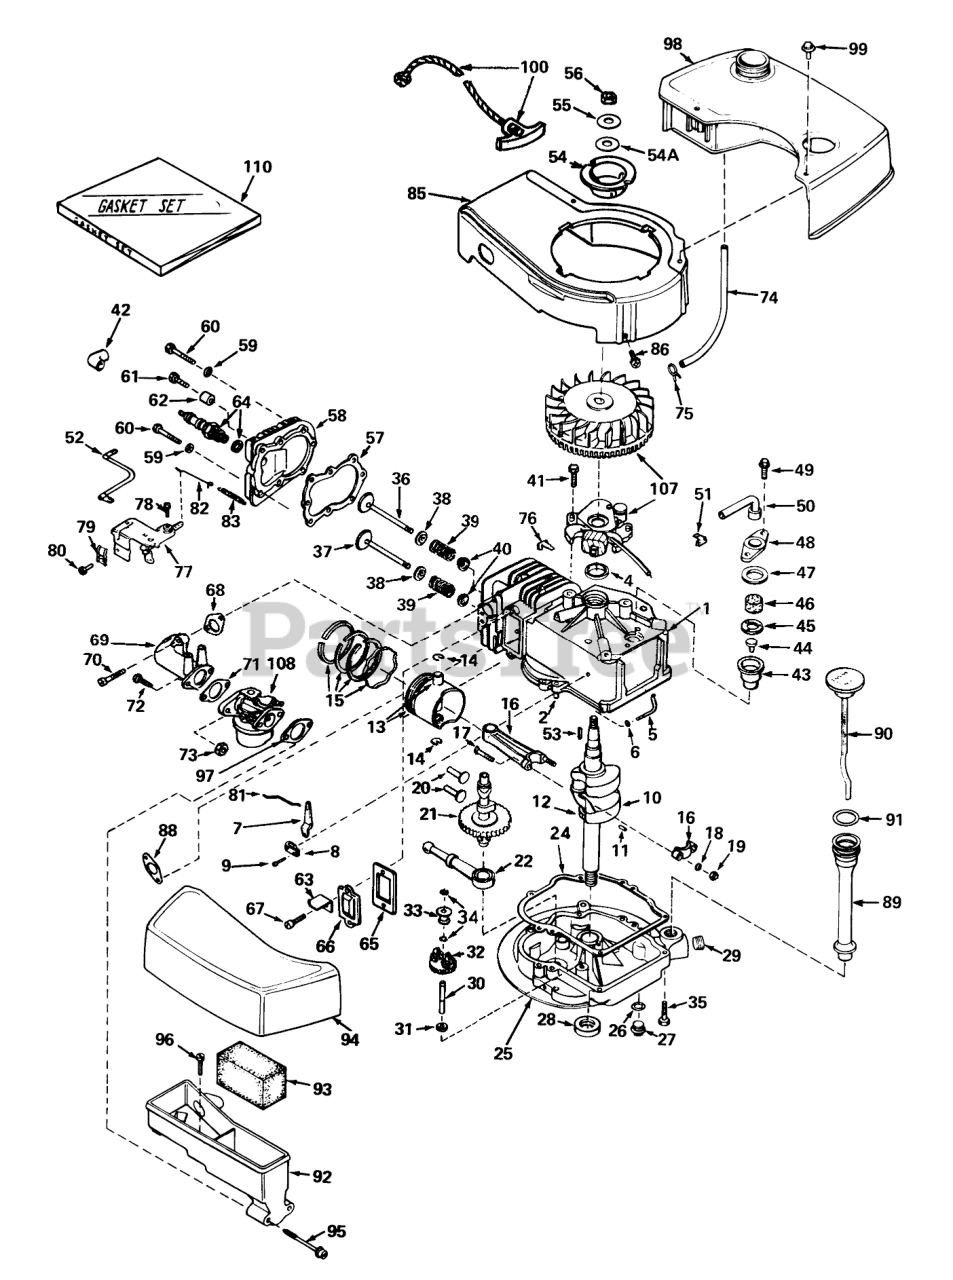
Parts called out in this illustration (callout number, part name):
1	Cylinder Assembly (Incl. Nos. 2, 4 and 87)
2	Pin-Dowel
4	OIL SEAL
5	Rod Governor (Incl. No. 6)
6	Washer-Flat
7	Governor Lever
8	Clamp-Lever, Governor
9	Screw
10	Crankshaft (Incl. Nos. 11 and 12)
11	Pin, Groove
12	Gear, Crankshaft
13	Piston & Pin Assembly (Incl. 2 of No. 14) (Standard)
13	Piston & Pin Assembly (Incl. 2 of No. 14) (.010 Oversize)
13	Piston & Pin Assembly (Incl. 2 of No. 14) (.020 Oversize)
14	Ring-Retaining, Piston Pin
15	Ring Set Piston (Std.)
15	Ring Set Piston (.010 Oversize)
15	Ring Set Piston (.020 Oversize)
16	Rod Assembly, Connecting (Incl. Nos. 17, 18 and 19)
17	Bolt, Connecting
19	LOCKNUT
20	Lifter-Valve
21	Camshaft (Mech. Compression Release)
22	Oil Pump ASM
24	Gasket, Mounting
25	Flange Assembly, Mounting (Incl. Nos. 27 thru 30)
26	Gasket-Oil Drain
27	Plug Oil Drain
28	Seal Oil
29	Plug Oil Drain
30	Shaft-Governor
31	Washer-Flat
32	Governor Gear ASM
33	Spool-Governor
34	Ring-Retaining
35	Screw (1/4-20 x 1-1/4)
36	Valve, Intake (Incl. Nos. 38 thru 40) (Standard)
36	Valve, Intake (Incl. Nos. 38 thru 40) (1/32" Oversize)
37	Valve, Exhaust (Incl. Nos. 38 thru 40) (Standard)
37	Valve, Exhaust (Incl. Nos. 38 thru 40) (1/32" Oversize)
38	Cap-Upper Valve Spring
39	Spring-Valve
40	Cap-Valve, Spring
42	Cover-Spark Plug
43	Body Breather Tube
44	Valve Check
45	2000A37 WIZARD ROTA
46	Element-Breather
47	Gasket-Breather
48	Cover Breather
49	Screw, Hex Hd. w/Conical
50	Tube, Breaker
51	Clip, Breather
52	Wire, Ground
53	Key Flywheel
54	Pulley Starter
54A	Washer Flat
55	Washer, Belleville
56	Nut, Flywheel
57	63573 GIL 42 SNWTHW
58	Head Cylinder
60	Screw
61	Screw Hex Hd. Cap
63	Retainer Clip
64	Plug, Spark (J17LM or equiv.)
65	Gasket-Breather
66	Cover-Valve
68	Gasket, Intake
69	Pipe, Intake
70	Screw (1/4-20 x 1)
71	Gasket-Carburetor
72	Screw
73	Nut and Lock Washer (1/4-28)
74	Line-Fuel
75	Clamp-Line, Fuel
76	Clip-Wire
77	Control Assy., Speed
78	Screw (10-24 x 3/4)
79	Conduit
80	Screw (10-32 x 3/8)
81	Link Governor
82	Link Governor Spring
83	Spring Governor
85	53024/VAR.GT O/P W/
86	Screw
88	Gasket Exhaust
89	Tube, Oil Filler
90	Dipstick, Oil (Incl. No. 91)
92	Body Air Cleaner
93	Filer, Air
94	Cove, Air Cleaner
95	Screw Fil Hd.
96	Screw, Hex Hd.
97	Gasket-Air Cleaner
98	Tank Fuel
99	Screw (10-32 x 35/64)
100	Rope Assy., Starter
107	Magneto
108	Carburetor (Incl. No. 71)
110	53024/VAR.16HP O/P
